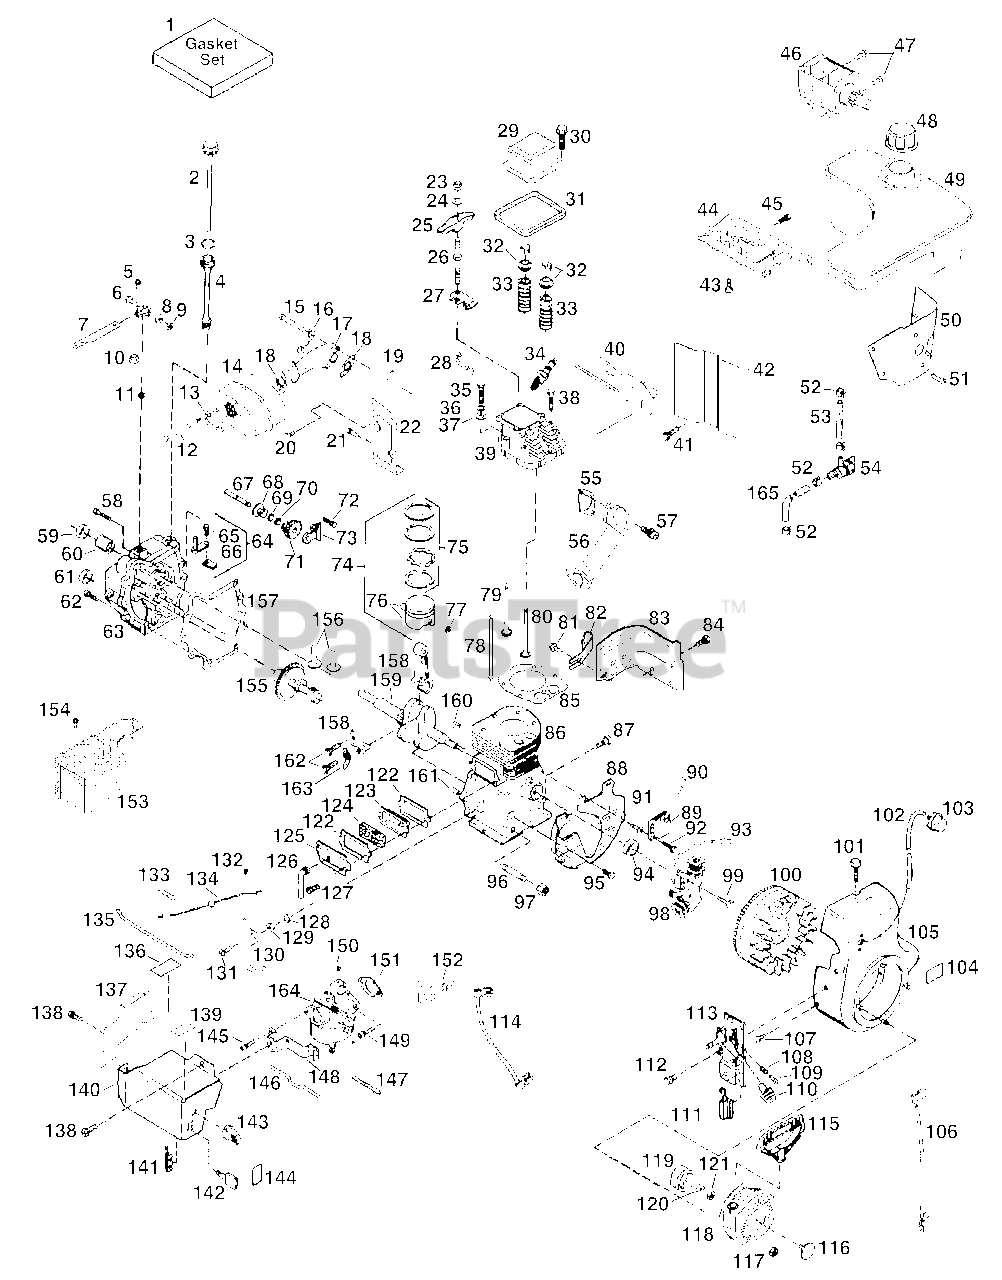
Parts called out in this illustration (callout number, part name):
1	Gasket Set
4	Oil Fill Tube
5	Screw, Torx T-15, 8-32 x 3/8"
6	Screw, 10-32 x 3/4"
7	Governor Lever
8	Lock Washer
9	Lock Nut, 10-32
10	Lock Nut, 10-32
11	Retaining Ring
12	Screw, 5/16-18 x 4-1/2"
13	Locking Plate
15	Screw, 5/16-18 x 1-9/32"
16	Locking Plate
17	Exhaust Manifold
18	Exhaust Gasket
19	Exhaust Port Liner
20	Screw, Torx T-30, 1/4-20 x 1/2".
21	Lock Nut, 10-32
22	Blower Housing Extension
24	Lock Washer
25	Rocker Arm
26	Rocker Arm Stud
27	Push Rod Guide
28	Locking Plate
29	Rocker Arm Cover
30	Screw, Torx T-30, 1/4-20 x 1/2"
31	Rocker Arm Cover Gasket
32	Valve Spring Keeper
33	Valve Spring
34	Spark Plug (RN4C)
35	Screw, 5/16-18 x 2-1/2"
36	Belleville Washer
38	Screw, Torx T-30, 1/4-20 x 15/32"
39	Cylinder Head
40	Cylinder Head Cover
41	Screw, 10-32 x 1/2"
42	Heat Baffle
43	Screw, 1/4-15 x 3/4"
44	Fuel Tank Bracket
45	Screw, 5/16-18 x 7/8"
46	Electric Starter Motor (110 Volt)
47	Screw, Torx T-30, 1/4-20 x 15/32"
48	Fuel Cap
49	Fuel Tank
50	Fuel Tank Extension
51	Screw, 10-32 x 1/2"
52	Fuel Line Clamp
53	Fuel Line
54	Fuel Shut-Off Valve
55	Intake Pipe Gasket
56	Intake Pipe
57	Screw, Torx T-30, 5/16-18 x 7/8"
58	Screw, 1/4-20 x 1-3/16"
60	Crankshaft Bushing
61	Camshaft Seal
62	Screw, 1/4-20 x 1-11/16"
63	Cylinder Cover
64	Governor Rod Ass’y
65	Screw, 6-40 x 5/16"
66	Governor Yoke
67	Governor Shaft
68	Governor Spool
70	Retaining Ring
71	Governor Gear Ass’y
72	Screw, 10-24 x 1/2"
73	Governor Gear Bracket
74	Piston, Pin & Ring Set (Std.)
75	Ring Set (Std.)
76	Piston & Pin Ass’y (Std.)
77	Piston Pin Retaining Ring
79	Exhaust Valve (Std.)
80	Intake Valve (Std.)
81	Screw, 10-24 x 3/16"
82	Fill Tube Clip
83	Blower Housing Extension
84	Screw, Torx T-30, 1/4-20 x 1/2"
85	Cylinder Head Gasket
86	Cylinder
87	Screw, 1/4-20 x 1/2"
88	Blower Housing Baffle
89	Solid State Ignition
90	Spark Plug Cover
91	Solid State Mounting Stud
92	Screw, Torx T-15, 10-24 x 15/16"
95	Screw, 1/4-20 x 5/8"
96	Oil Drain Extension
97	Extension Cap
98	Alternator Coil (18 Watt)
99	Screw, 1/4-20 x 3/4"
100	Flywheel (W/Ring Gear)
101	Screw, 1/4-20 x 5/8"
102	Primer Line
103	Primer Ass’y
104	Primer Decal
105	Blower Housing
106	Ground Wire
107	Screw, Torx T-40, 5/16-24 x 21/32"
108	Compression Spring
109	Screw, Torx T-10, 5-40 x 7/16"
110	Control Knob
112	Screw, 10-32 x 1/2"
113	Control Bracket
114	Ground Wire
115	Starter Handle
116	Starter Decal
117	Nut & Lock Washer, 1/4-28
118	Rewind Starter
119	Cylinder Head Gasket
120	Lock Washer
121	Flywheel Nut
122	Valve Cover Gasket
123	Breather Body
124	Breather Element
125	Valve Cover
126	Breather Tube
127	Screw, 10-24 x 1/2"
130	Bellcrank Lever
131	Screw, 10-24 x 29/32"
133	Extension Spring
134	Governor Link
135	Throttle Link
136	Warning Decal
137	Carburetor Cover
138	Screw, 10-32 x 1/2"
139	Caution Decal
140	Carburetor Cover (Front)
142	Key Switch
143	Choke Knob
144	Choke Decal
145	Screw, 10-32 x 1/2"
146	Choke Spring
147	Choke Rod
148	Choke Bracket
149	Screw, 1/4-20 x 27/32"
151	Carburetor To Intake Pipe Gasket
152	Key Switch Bracket
153	Heat Shield
154	Screw, 10-32 x 5/16"
155	Camshaft (MCR)
156	Valve Lifter
157	Cylinder Cover Gasket
158	Connecting Rod Ass’y
159	Crankshaft
160	Flywheel Key
161	Dowel Pin
162	Connecting Rod Bolt
163	Oil Dipper
164	Carburetor
165	Fuel Line
